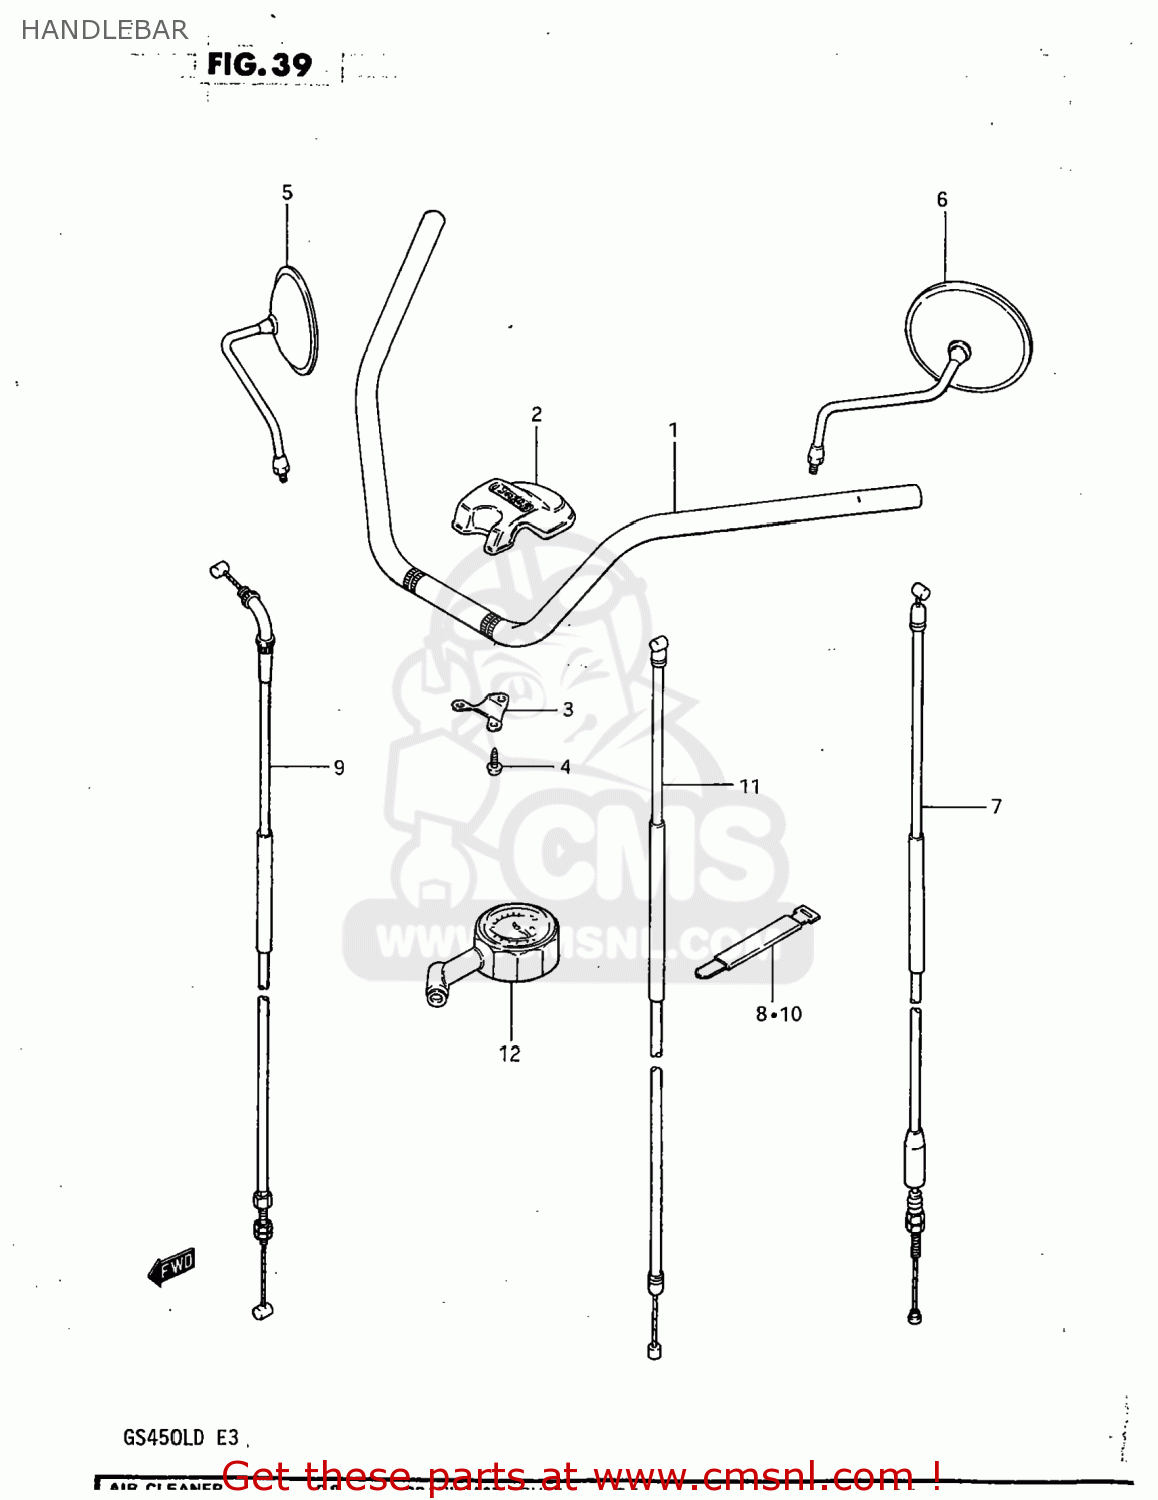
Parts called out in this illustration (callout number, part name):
1	HANDLEBAR,RIGHT
2	COVER,STEERING HEAD
3	BRACKET,HEAD COVER
4	SCREW
5	MIRROR ASSEMBLY,RIGHT
6	MIRROR ASSEMBLY,LEFT
7	CABLE ASSEMBLY,CLUTCH
8	CLAMP
9	CABLE ASSEMBLY,THROTTLE
10	CLAMP
11	CABLE ASSEMBLY,STARTER
12	GAUGE ASSY,AIR PRESSURE
